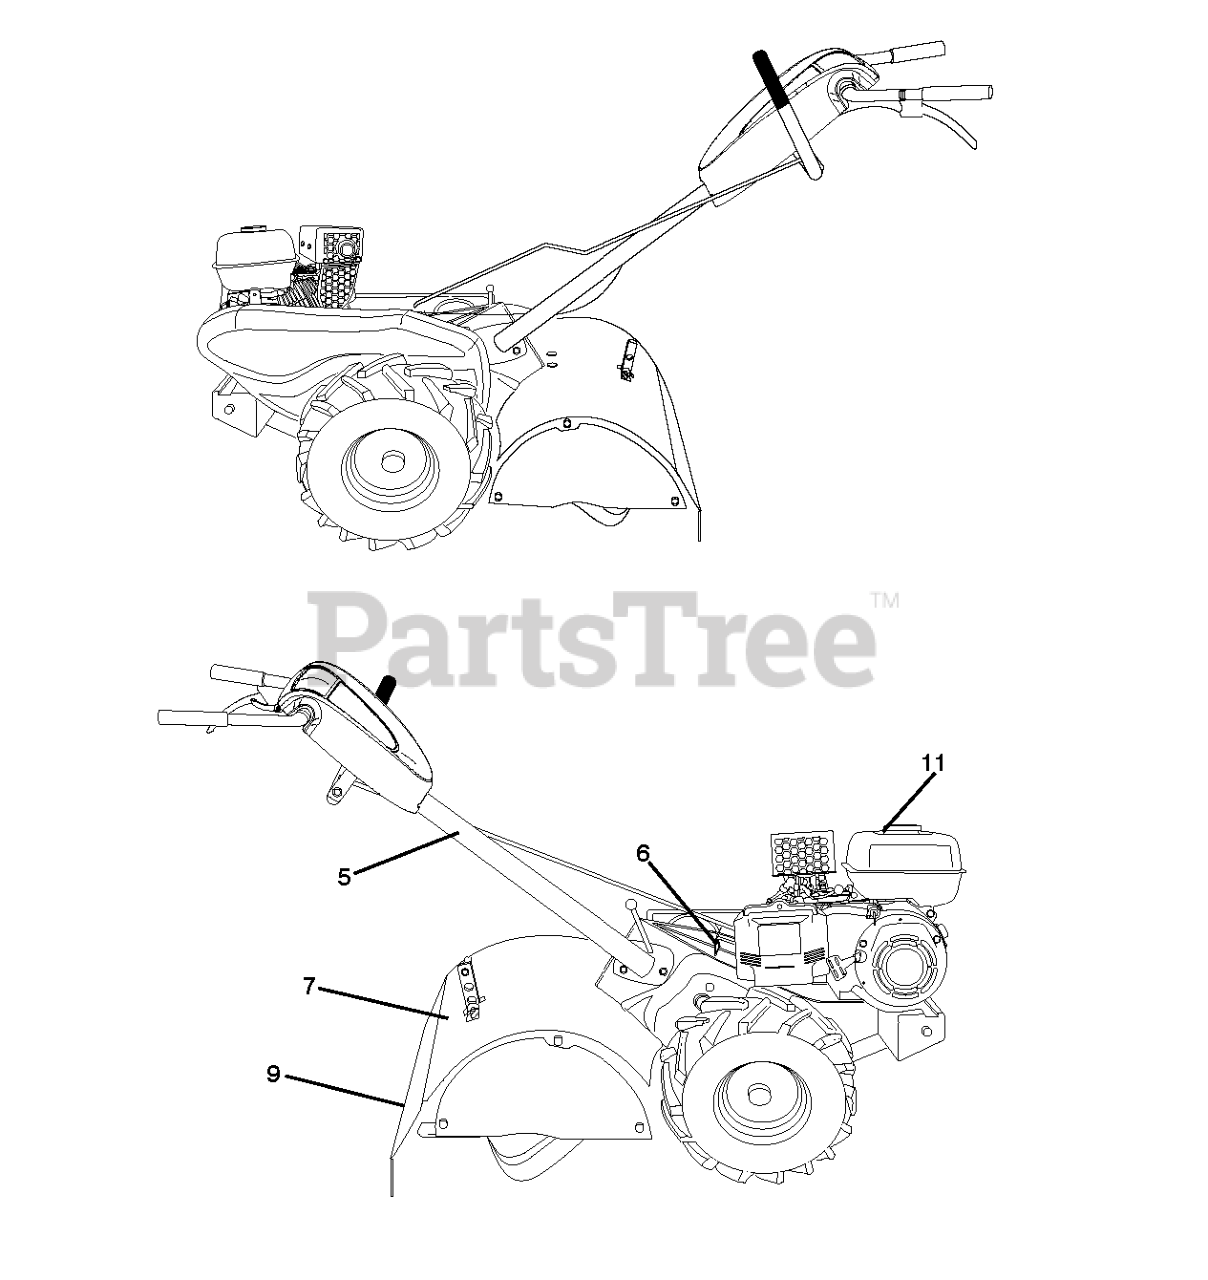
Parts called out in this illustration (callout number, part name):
5	DECAL TI (2 2)
6	DECAL.SHIFT.INDICATOR.TILLER
7	DECAL.WARNING.SHLD.ENG/FR
9	DECAL TI
11	DECAL.ETHANOL.E85 WARNING SYMB
